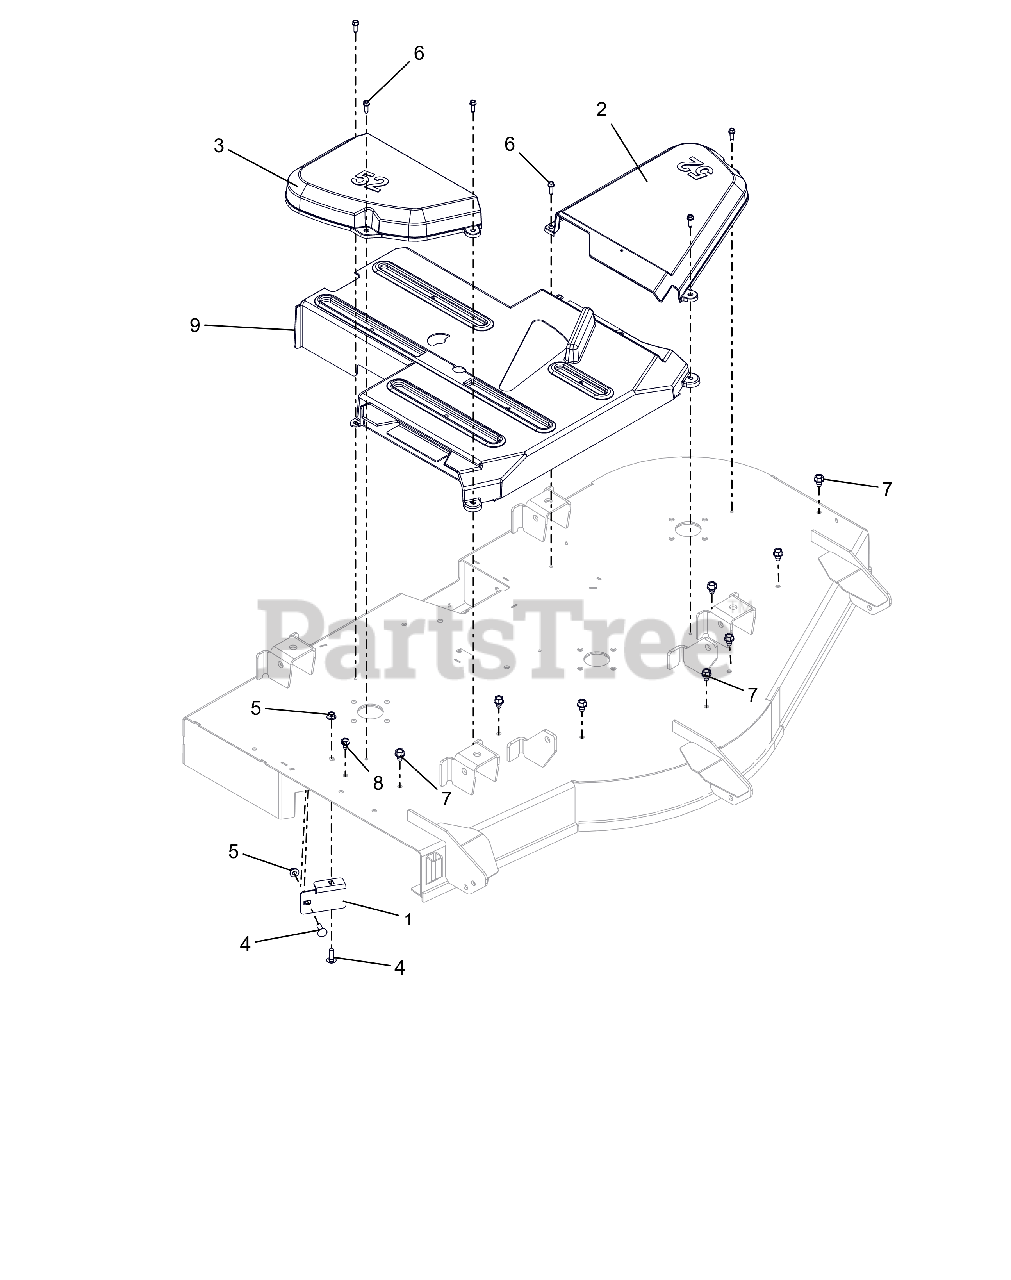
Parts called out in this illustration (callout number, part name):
1	STRIP, DEFLECTOR - 52"
2	COVER, BELT 52" LH
3	COVER, BELT 52" RIGHT
4	BLT,RHSN .31-18X1.00 G5 ZCC
5	NUT,LK-NYL-FLG .31-18 G5ZC120
6	SCR,TAP .25-20X.75 HWH TR ZCC
7	SCR,TAP .375-16X.50 HWH TR ZCC
8	SCR,TAP .312-18X.50 HWH TR ZCC
9	GUARD, CENTER, DECK
